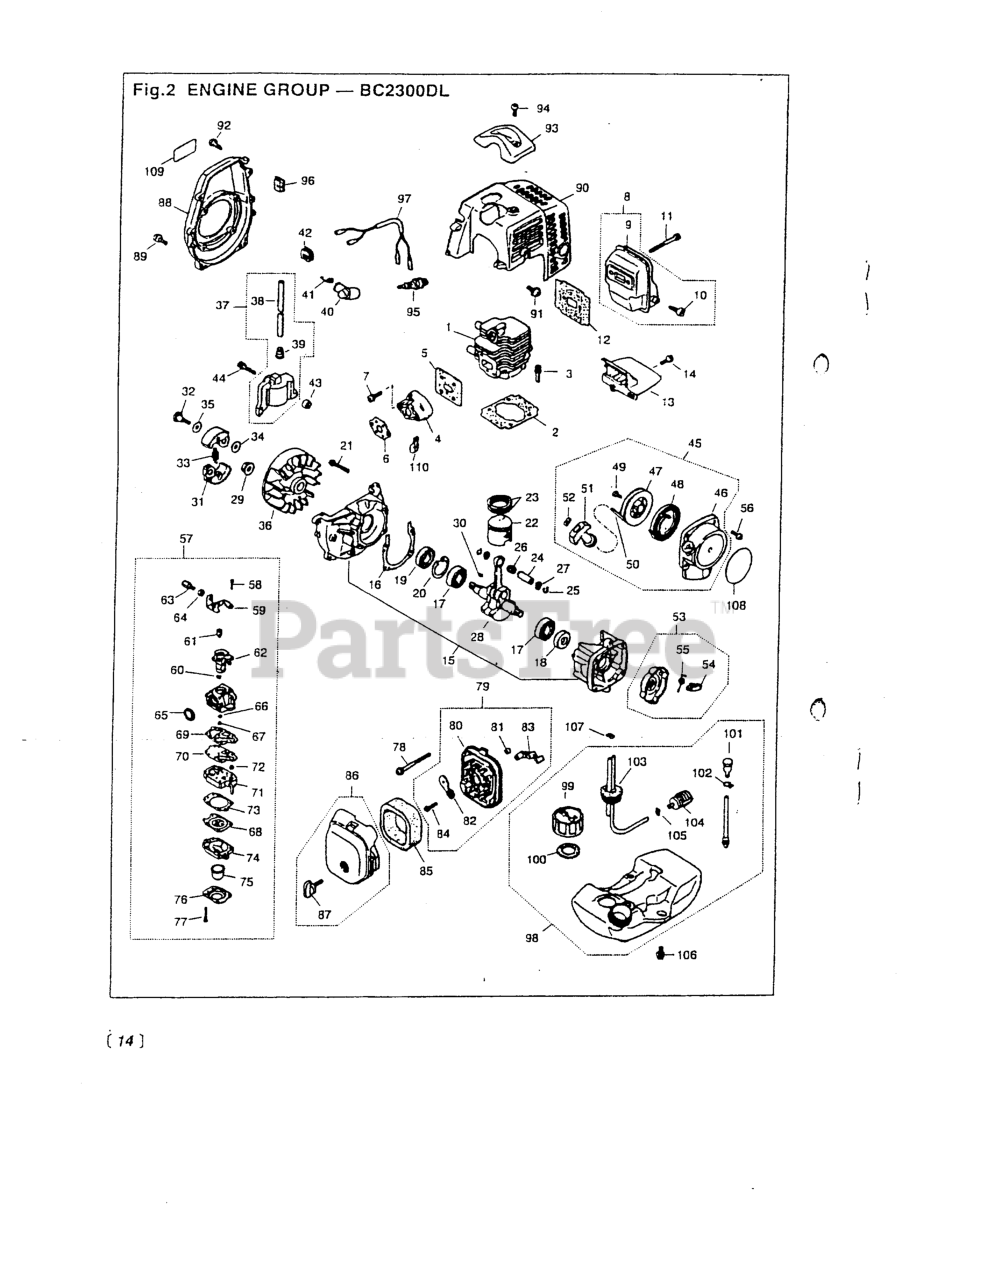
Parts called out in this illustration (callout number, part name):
1	CYLINDER
3	BOLT, M5 X 22
7	SCREW, M5X20 (RPLS.1400-75510)
9	MUFFLER ASSY (USE 5913-15100)
10	ARRESTER (RPLS 5850-15140)
11	BOLT, M5 x 50
12	GASKET, MUFFLER
14	SCREW, M4 X 16
15	CRANKCASE
17	BEARING
18	SEAL, OIL (RPLS 1100-21210)
19	SEAL, OIL (RPLS 1140-21220)
20	RING, SNAP, M28 x 1.2
21	BOLT, M5 X 30
22	PISTON (REPLACES 1140-41110)
23	RING, PISTON (RPLS 1850-41210)
24	PIN, PISTON 5x8x26
25	RING, SNAP (RPLS 1101-41320)
27	WASHER
28	CRANKSHAFT (RPLS 1850-42000)
30	KEY
32	BOLT
33	SPRING, CLUTCH (RPLS-51220)
34	WASHER, FLAT (USE 182303)
38	CORD
39	CAP
41	SPRING
42	GROMMET
44	BOLT
45	RECOIL ASSEMBLY
46	CASE
47	REEL
48	SPRING, SPIRAL
49	SCREW (RPLS -75150)
51	KNOB
52	PLATE, STOPPER
53	PULLEY ASSY (RPLS -75210)
54	RATCHET (RPLS 1850-75220)
55	SPRING, RETURN
56	SCREW, M4 X 16
57	CARBURETOR
58	SCREW
60	RING
61	SWIVEL
62	VALVE ASSY
63	SCREW, CABLE ADJUSTER
64	NUT, CABLE ADJUSTER
65	RING, PACKING
66	RING, O
67	JET
68	DIAPHRAGM (USE 4810-81260)
69	GASKET, PUMP
70	DIAPHRAGM
71	BODY, PUMP
73	GASKET, DIAPHRAGM
74	BODY, PURGE
75	COVER
76	COVER, PUMP
77	SCREW
78	SCREW, M5 X 55
80	BODY
81	SLEEVE
82	PLATE, CHOKE (RPLS-82130)
83	LEVER, CHOKE
84	SCREW (REPLACES 50030272)
85	ELEMENT
89	SCREW, M5X20 (RPLS.1400-75510)
91	SCREW, M5 x 12
92	SCREW, HOUSING
93	GUARD, PLUG
94	SCREW,M5 X 14 (RPLS 1400-15510
97	CORD COMP (RPLS -73200)
99	CAP (RPLS -85200)
100	PACKING
102	CLIP
103	PIPE COMPLETE
104	FILTER ASSY
105	CLIP (REPLACES 2841-31280)
106	SCREW
107	CLIP
109	LABEL, FAN COVER
110	CLAMP
